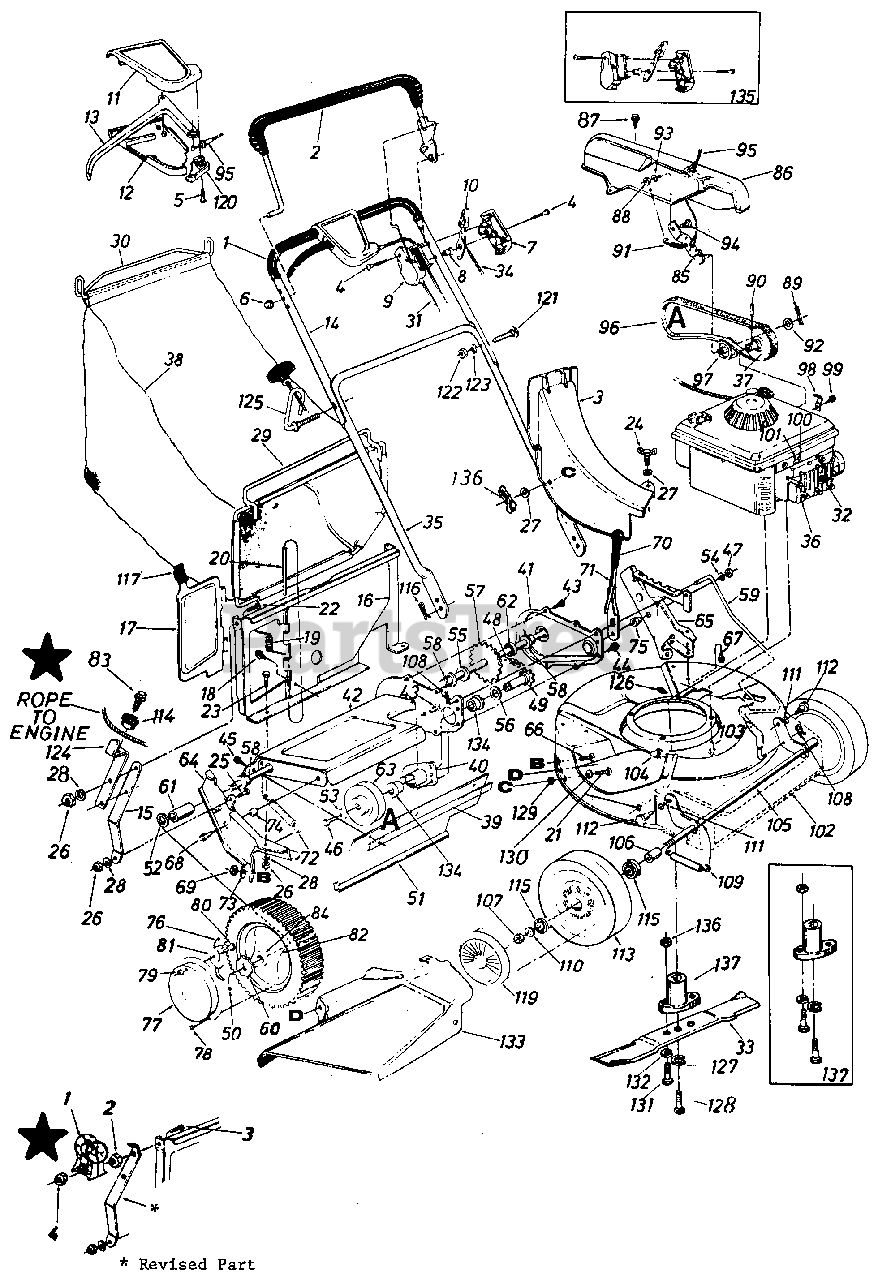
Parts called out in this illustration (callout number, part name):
2	Control Handle Ass'y. -L.H.
3	Top Discharge Chute Ass'y.
4	Truss Mch. Scr. #12 x 1.50" Lg.
5	Fl-"C"-Sunk Hd. Tap Scr. #10 x .75" Lg.
6	Cap Speed Nut .31 Dia.
7	Control Panel Half
8	Control Disc Pin
9	Clutch Panel Half
10	Throttle Control Lever
11	Self-Propelled Control Cover
12	Self-Propelled Control Cover
13	Control Lever
14	Upper Handle Chrome
15	Panel Support Brkt.
16	Top Catcher Panel
17	Top Door
18	Hex "B" Tap Scr. #10 x .38" Lg.
19	Torsion Spring .20" I.D. x 1.14" Lg.
20	Pivot Pin .187" Dia. x 7.25" Lg.
21	Carriage Bolt 1/4-20 x .62" Lg .
22	Truss Mach. Scr. 1/4-20 x 75" Lg.
23	Hex Bolt 1/4-20 x .50" Lg.
24	Wing Bolt 1/4-20 x .62" Lg.
25	Hex Bolt 1/4-20 x .62" Lg.
26	Hex Nut 1/4 -20 Thd.
27	Fl-Wash. .280" I.D. x .620" O.D.
28	L-Wash. 1/4" I.D.
29	Front Grass Catcher Frame
30	Grass Catcher Handle
31	Control Cable 43" Lg.
32	Spark Plug Insulator
33	21" Blade
34	Throttle Control Wire 58.0"
35	Lower Handle Chrome
36	Engine
37	Engine Pulley 1/2"
38	21" Top Discharge Grass Bag
39	Retaining Strip
40	Bearing Hub Flange Ass'y.
41	Chain Cover
42	Chain Axle Ass'y.
43	Hex B-Tap Scr. 1/4" x .38"Lg.
44	Hex Wash. S-Tap Scr. 1/4-20
45	Hex AB-Tap Scr. 1/4 X .62"Lg.
46	Hex Wash. TT-Tap Scr. 1/4-20
47	Hex Patch L-Nut 3/8-24 Thd.
48	#48 Chain .500" Pitch x .30 Links
49	Sprocket Shaft Ass'y.
50	Cotter Pin 118" Dia. x 1.00" Lg.
51	Rear Flap 3.75" x 17.30" Lg.
52	Fl-Wash. .531" I.D. x .930" O.D.
53	Bell-Wash. .26511 I.D. x .75" O.D.
54	Fl-Wash. .385" I.D. x .87" O.D.
55	Fl-Wash. .5101' I.D. x 1.0" O.D.
56	Fl-Wash. .62" I.D. x 1.12"
57	Rear Shaft Ass'y. 22.05" Lg.
58	Hex Flange Bearing .506" I.D. Plastic
59	Height Adj. Rod 1.50" x 19.42" Lg.
60	Ratchet Wheel 1.62" O.D.
61	Spacer .51" I.D. x .69" O.D. x.690" Lg.
62	Spacer.510" I.D. x 1.00" O.D. x .210" Lg.
63	1/2""V"-Pulley
64	R.H. Handle Wheel Brkt. Ass'y.
65	L.H. Handle Wheel Brkt. Ass'y.
66	Carriage Bolt 5/16-18 x .62"
67	Hex Wash. Hd. B-Tap Scr. 5/16-18
68	Hex Wash. Hd. TT-Tap Scr. 3/8-1 6
69	Hex Nut 5/16-18 Thd.
71	Height Adj. Lever 1.25 x 8.5" Lg.
72	Extension Spring .50" O.D. x 3.80" Lg.
73	Bell-Wash. .345" I.D. x .88" O.D.
74	Spacer.385" I.D. x .502" O.D. x .270" Lg.
75	Shld. Spacer.500" Dia. x .100
76	Spring Nylon
77	Hub Cap
78	Pan Hd. Tap Scr. #12 x .50" Lg.
79	Hex Ins. L-Nut 1/4-20 Thd.
80	Shld. Scr. .342" Dia. x .268
81	Pawl
82	Wheel Ass'y. Comp. Rear 8 x 1.75
83	Hex Wash. Hd. Tap Scr. 3/8-16 x 1.00" Lg.
84	Flange Ball Bearing 1/2" I.D.
85	Belt Idler Bracket Ass'y.
86	Belt Cover
87	Hex Wash. S-Tap Scr. 1/4-20 x.50" Lg.
88	Hex Nut 1/4Thd.
89	Cotter Pin 118" Dia. x 1.00" Lg.*
90	Spring Pin Spir. 3/16" Dia. x 1.00" Lg.
91	Extension Spring .33" O.D. x 1.12" Lg.
92	Fl-Wash. .531" I.D. x .930" O.D. x .050
93	L-Wash. 1/4" I.D.
94	Shld. Bolt .375" Dia. x .181
95	S.P. Cable x 53.0" Lg.
96	"V"-Belt 1/2" X 32.0" Lg.
97	Fl-ldler Plastic 1.62" Dia.
98	Throttle Control Cable Clip
99	Hex B-Tap Scr. #10 x .38" Lg .
100	Hex Sems Bolt #10-32 x .62" Lg.
101	Casing Clamp
104	Speed Nut 1/4-20 U-Type
105	Front Axle Ass'y.
106	Sleeve.526" I.D. x.690" O.D. x .880" Lg.
107	Hex L-Nut 1/2-20 Thd.
108	Intern. Cotter Pin 5/16" Dia.
109	Extension Spring .50" O.D. x 3.20" Lg.
110	Fl-Wash. .531" I.D. x.930" O.D.
111	Intern. L-Wash. 3/8 x .56" O.D.
112	Shld. Bolt .623" Dia. x .425N
113	Front-Wheel Ass'y. Comp. 7 x 1.75
114	Flanged Ball Bearing 3/8" I.D.
115	Flange Ball Bearing 1/2" I.D.
116	Intern. Cotter Pin 5/16" Dia.
117	Door Grip x 2.5
119	Hub Cap Plastic
120	S.P. Control Cover
121	Curved Carr. Bolt 5/16-18 x 1.38" Lg.
122	Hex Nut 5/16-18 Thd.*
123	L-Wash. 5/16" I.D.*
124	Rope Guide Brkt.
125	Rope Guide Bolt
127	L-Wash. 3/8" I.D. H.D.
128	Hex Bolt 3/8-24 x 2.25" Lg. (Grade 5)
129	Bolt Retainer 1/4 X .50" O.D.
130	Fl-Wash. .344" I.D. x .62" O.D.
131	Hex Bolt 5/16-24 x 1.00" Lg. (Grade 5)
132	L-Wash. 5/16" I.D.*
133	Side Chute Deflector
134	Flange Bushing
135	Kit Control Housing Comp.
136	Hex Nut 5/16-24 Thd.*
137	Blade Adapter Kit
